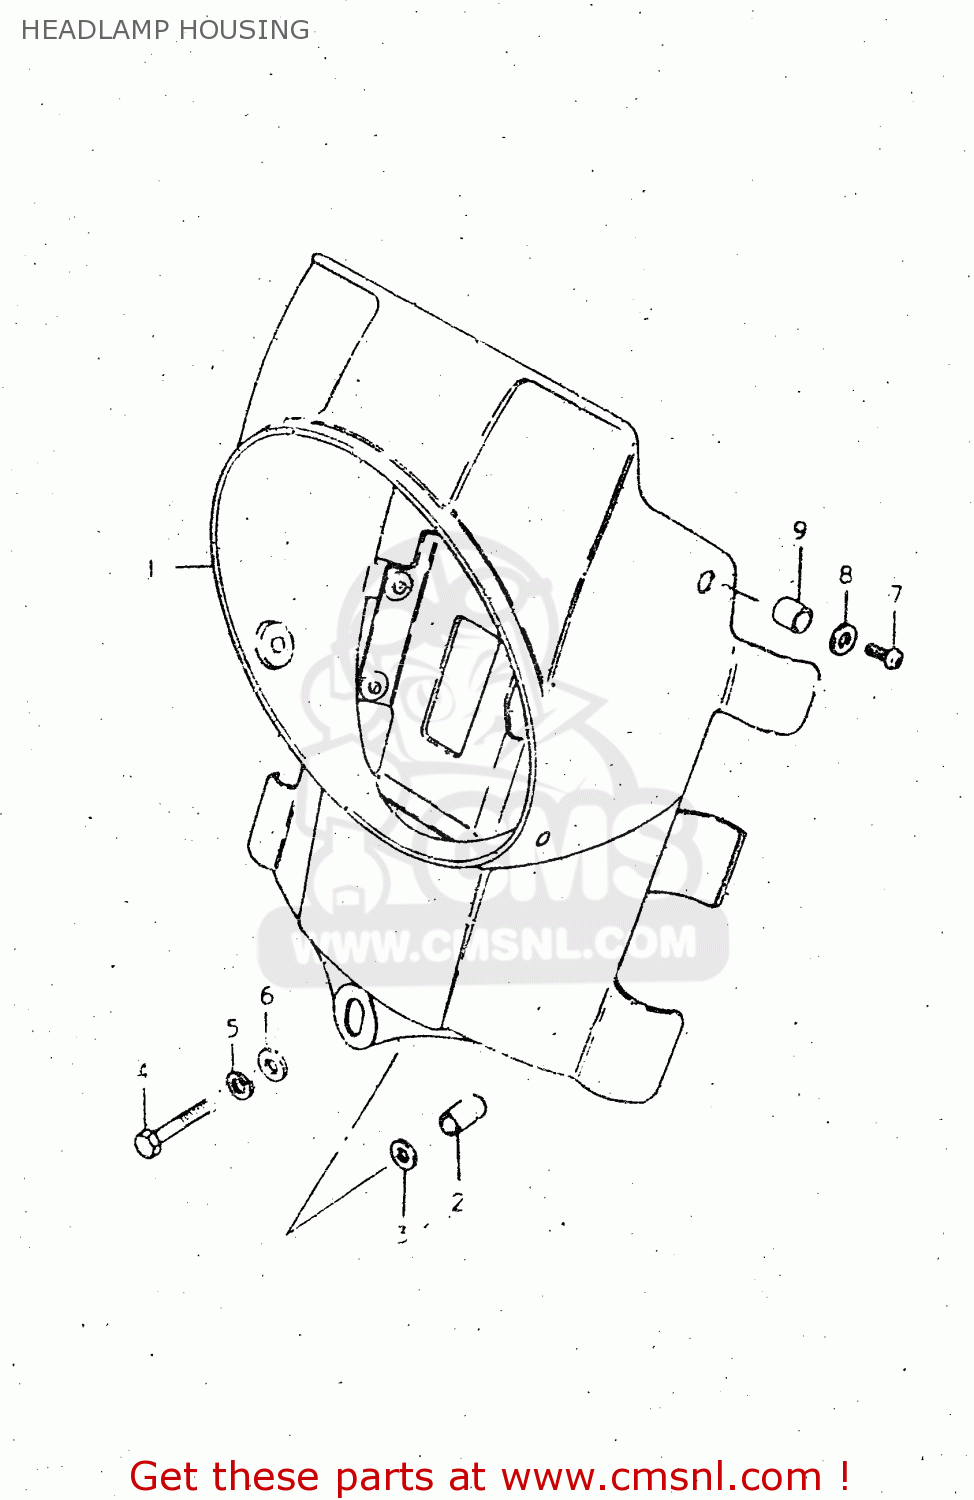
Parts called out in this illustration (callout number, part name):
1	HOUSING, HEADLAMP (RED)
2	SPACER (6.5X10.5X13.5)
3	WASHER
4	BOLT
5	LOCK WASHER
6	WASHER (6.5X20X1.2)
7	SCREW
8	WASHER (5.5X18X1.6)
9	SPACER (5.5X8X4)
